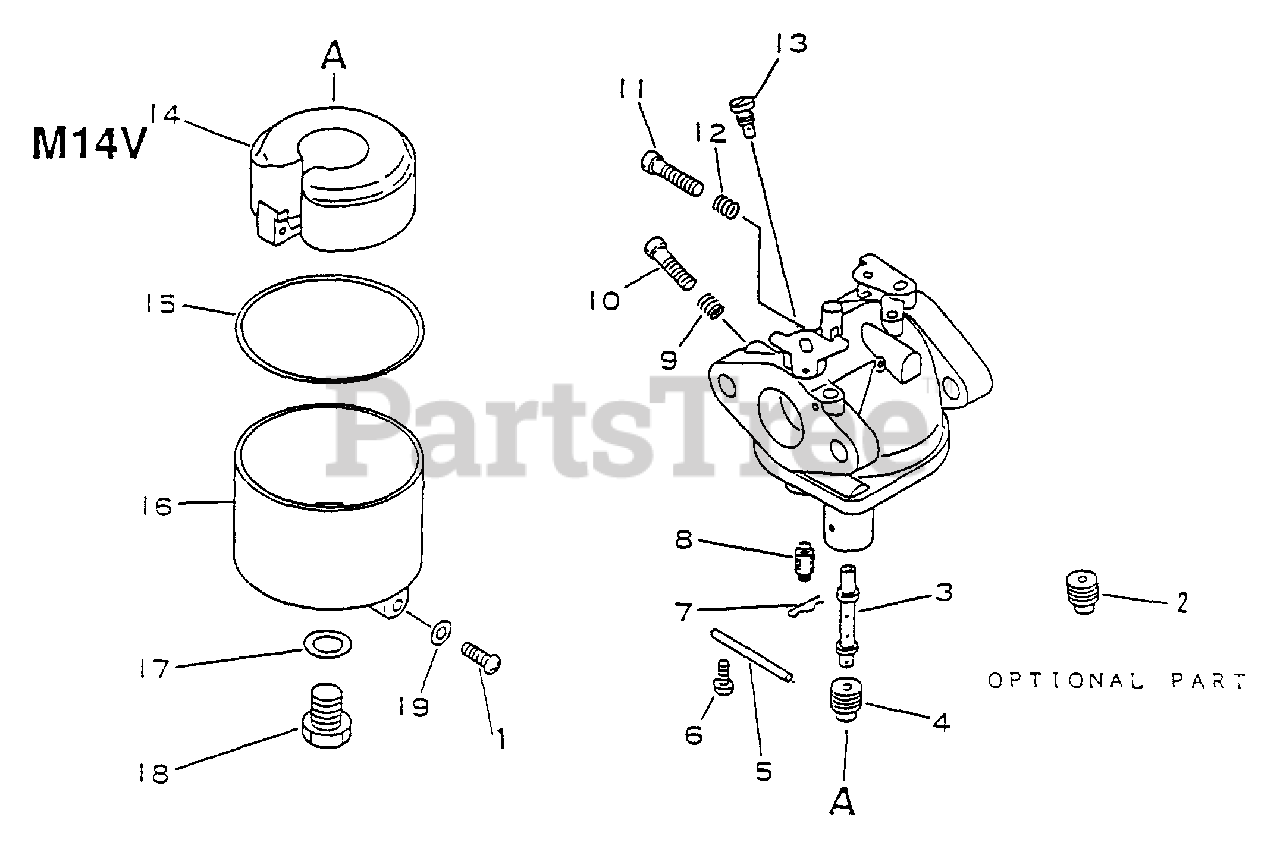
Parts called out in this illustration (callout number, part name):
1	SCREW 4×6
2	JET, MAIN
3	NOZZLE, MAIN
4	JET, MAIN
5	PIN, METERING LEVER
6	SCREW - 4×8
7	CLIP
8	VALVE, NEEDLE
9	SPRING
10	SCREW
11	SCREW, IDLE ADJUST
12	SPRING
13	JET, PILOT
14	FLOAT
15	GASKET, FLOAT CHAMBER
16	CHAMBER, FLOAT
18	BOLT
